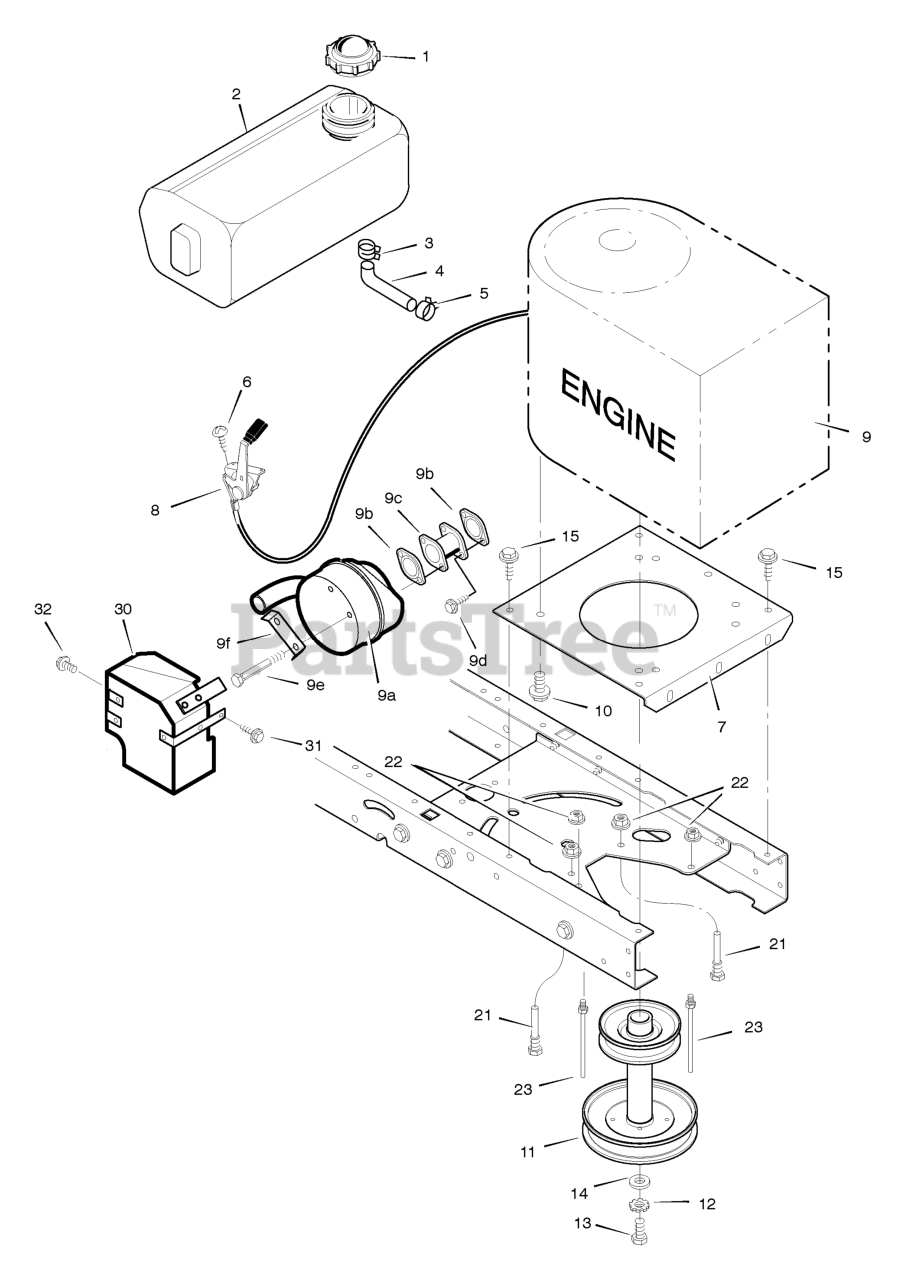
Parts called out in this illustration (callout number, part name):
1	Fuel Cap
2	Fuel Tank
3	Hose Clamp
4	Fuel Line (Must cut to length)
5	Hose Clamp
7	Plate, Engine
8	Throttle Control
9	Engine *
10	Bolt, Engine Mount
11	STACK PULLEY ASSEMBLY
12	Lockwasher
13	Bolt, Hex
21	Guide, Belt
22	Nut, Flange
23	Guide, Belt
30	Shield, Heat
